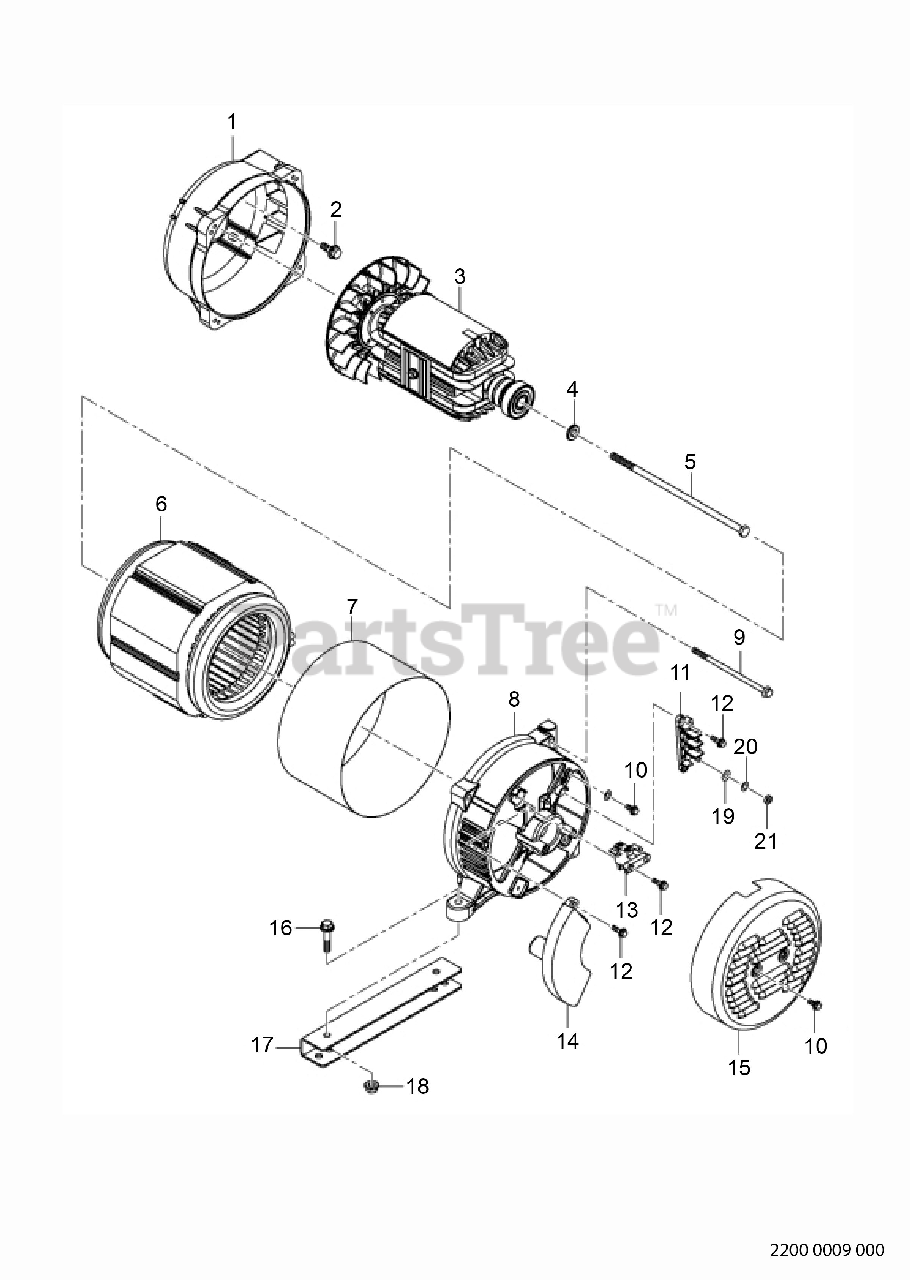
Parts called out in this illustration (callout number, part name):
1	FRONT BRACKET
3	ROTOR AY
5	BOLT
6	STATOR AY
7	STATOR COVER
8	REAR BRACKET
9	BOLT
10	BOLT
11	BASE
12	BOLT
14	AVR
16	FLANGE BOLT
17	MOUNT BASE
18	NUT FLANGE
19	WASHER
20	SPRING WASHER
21	NUT
